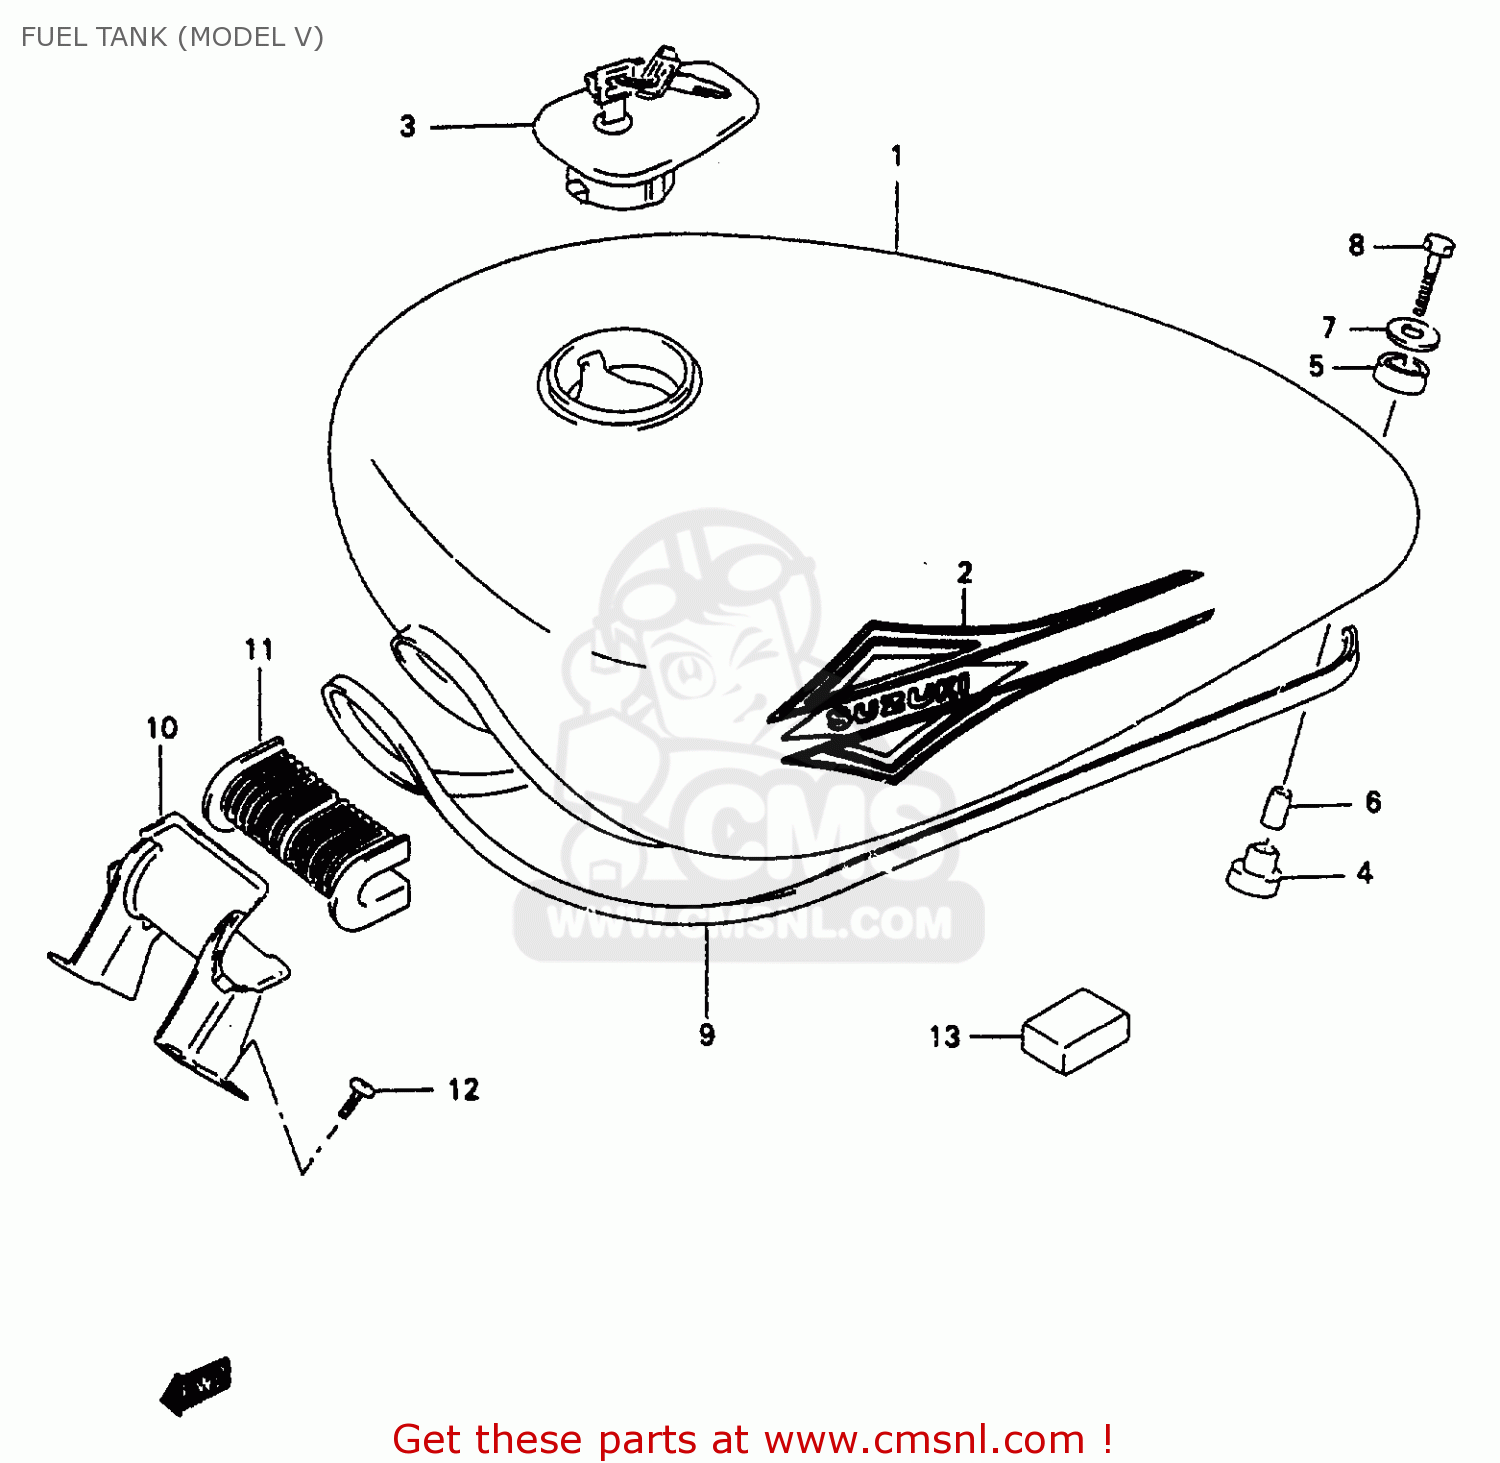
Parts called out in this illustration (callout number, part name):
1	TANK ASSY, FUEL (BLACK)
2	TAPE SET, FUEL TANK
3	CAP SET,FUEL TANK
4	CUSHION
5	CUSHION
6	SPACER(6.5X9X21.5)
7	WASHER (6.5X24X1.6)
8	SCREW
9	MOLDING
10	BRACKET,FUEL TANK FR
11	CUSHION,FUEL TANK FR
12	SCREW
13	CUSHION
